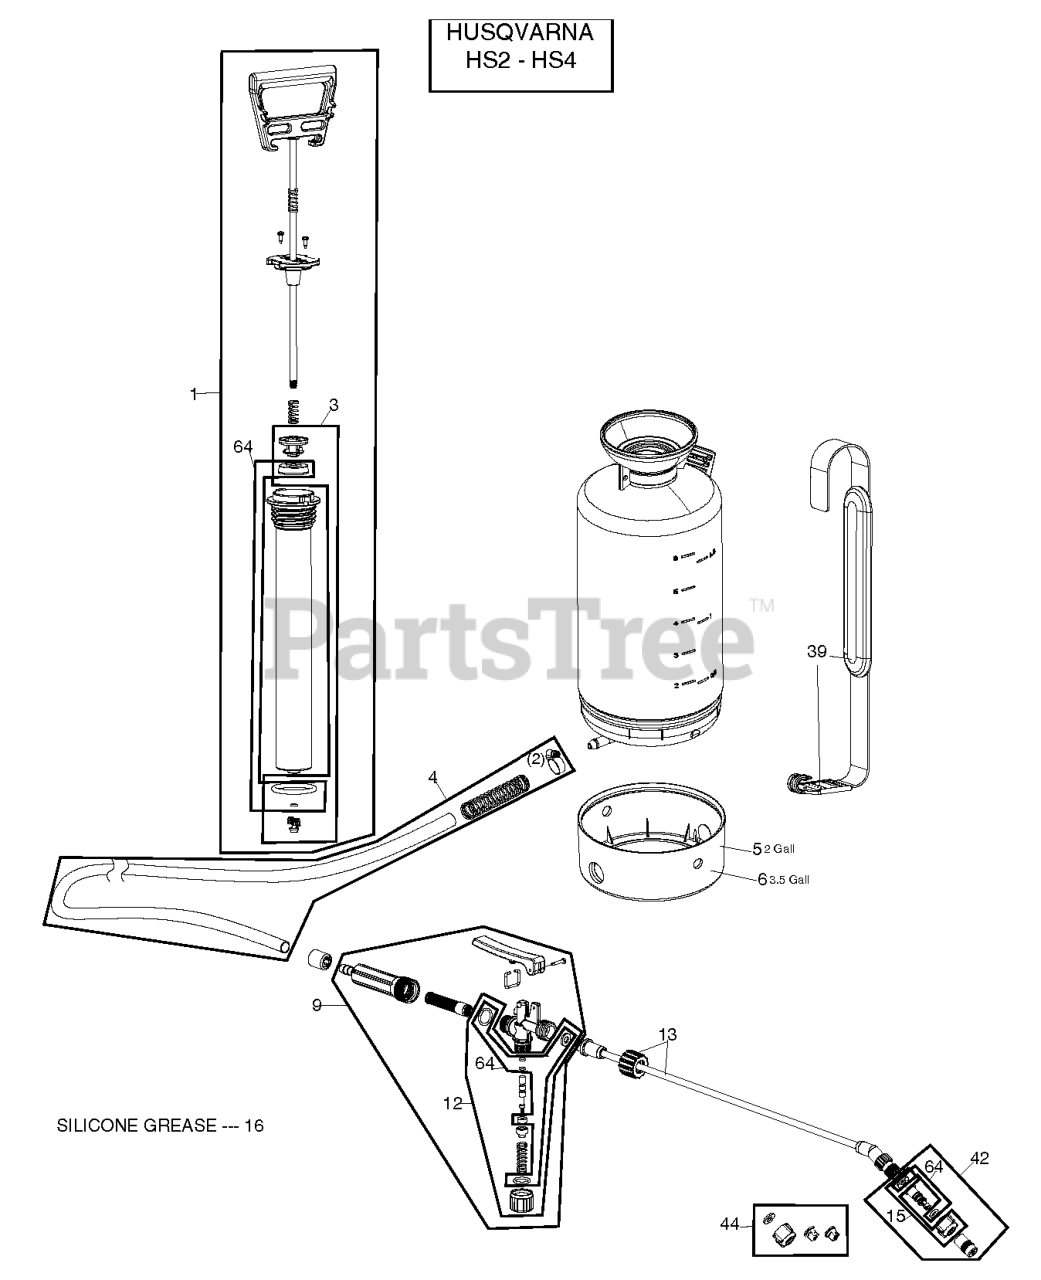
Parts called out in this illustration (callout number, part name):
1	COMPLETE PUMP MODULE ORANGE
3	CHECK VALVE ANTENNA & O-RING
4	HOSE AND 2 HOSE CLAMPS
5	BASE FOR 2 GAL COMPRESSION ORG
6	BASE 3 GALLON
8	SHOULDER STRAP ASSEMBLY
9	COMP SPRAY PISTOL WBUILTNFILTE
12	SPINDLE SET
13	BRASS SPRAY WAND 20"
15	NOZZLE HOLDER
16	SILICONE GREASE
39	PADDED SHOULDER STRAPS
41	BUCKLE & HOOK FOR STRAP
42	ADJ BRASS NOZZLE WITH HOLDER
44	PLASTIC SPRAY TIP SET (2-8004)
